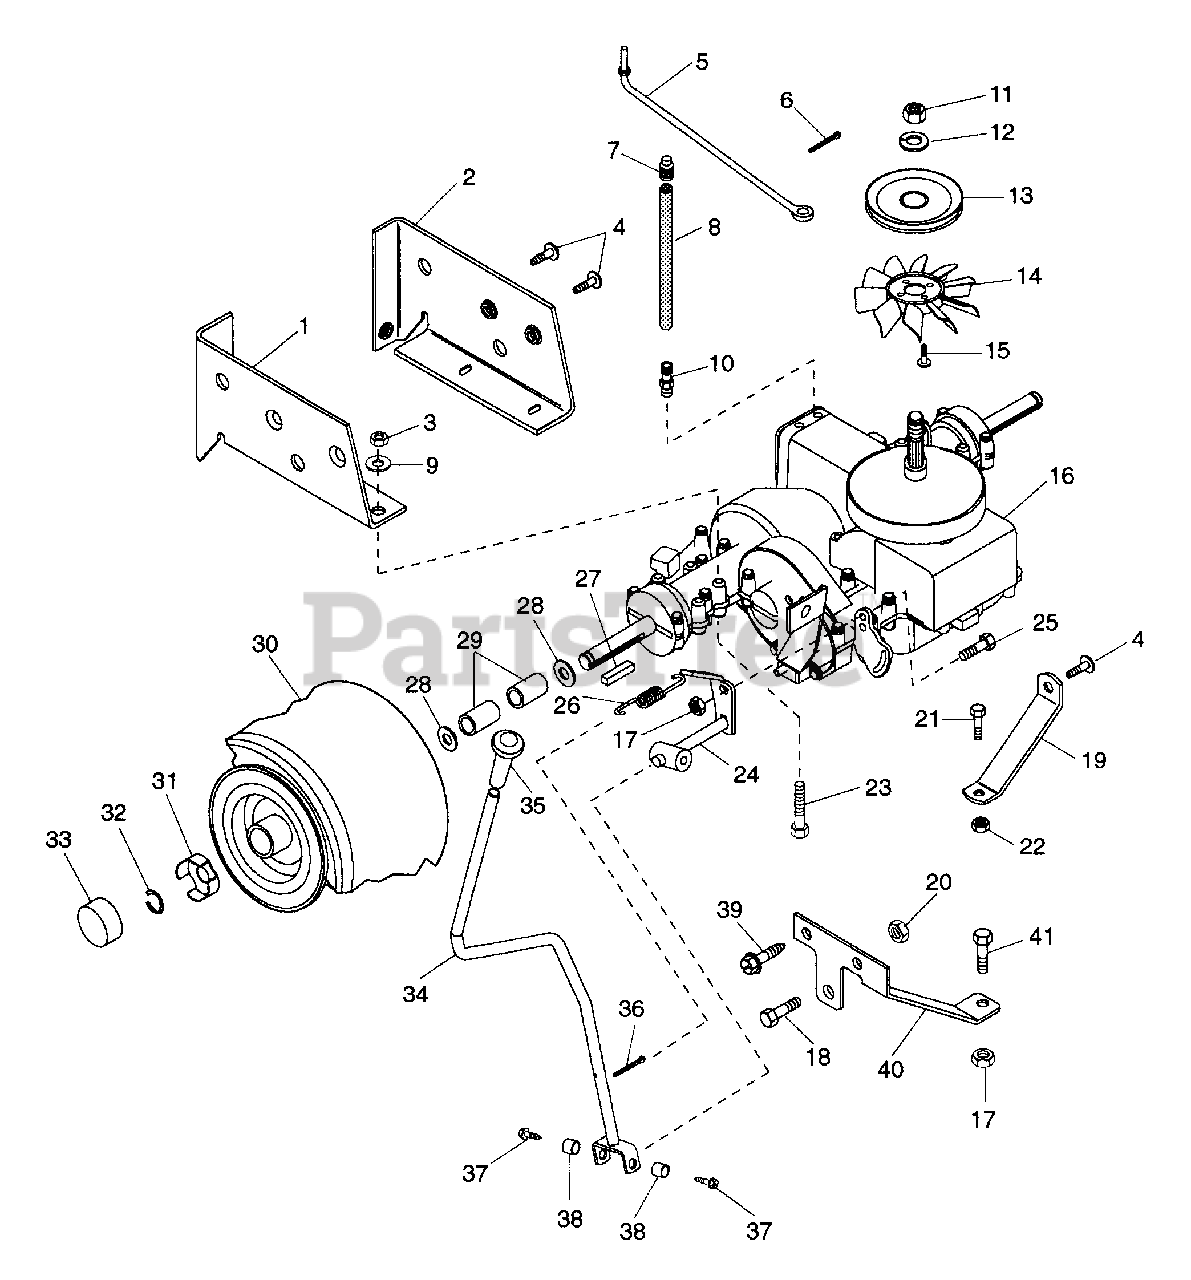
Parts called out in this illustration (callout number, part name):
1	MOUNT- TRANS. RH
2	MOUNT- TRANS. LH
3	NUT-LK-TOP .312-18 GR C PL
4	SCR-TAP .375-16X.75 HWH PL TR
5	ROD- TRANSMISSION DISCONNECT
6	PIN-COTR .09X.75 PL
7	CAP-VENT .50
8	HOSE- VENT .50ID X 7.50LONG
9	WSHR-FL-STL .328X.875X.062 PL
10	FTG-STR .50 O-RING
11	NUT-JAM .50-20 PL
12	WSHR-LK .50 REG.
13	SHEAVE - TRANSAXLE
15	SCR-TAP 10-32X.62 HWH PL T
16	TRANSAXLE- HYDRO #312-0750 IHT
17	NUT-LK .312-18 GR A PL
18	BLT-HEX .38-16X.75 PL GR5
19	TORQUE STRAP- LH
20	NUT-LK TOP .375-16 GR C YWZC
21	BLT-HEX .31-18X1.50 PL GR5
22	NUT-LK-NYL.312-18 PL
23	BLT-HEX .31-18X2.50 PL GR5
24	ARM - SHIFT
25	BLT-HEX .31-18X.75 PL GR2
26	SG-TENS .092X.69X1.75 WLD 54
27	KEY-SQ .188X2.0X.188 SAE 8630
28	WSHR-FL-STL .755X1.375X.062 PL
29	BSHG-SLV .750X1.125X1.062
30	T/WHL ASSY 20X8.00-8
30	RIM
30	TIRE 20X10-8 2P TS TL
31	SPINDLE CUP
32	RG-RTNG-EXT .750X.050
33	HUB CAP
34	LEVER - SHIFT
36	PIN-COTR .12X1.0 PL
37	SCR-TAP .312-18X.75 HWH PL TR
38	SPACER BUSHING .5 X .32 X .21
39	SCR-TAP .312-18X.50 HWH PL TR
40	TORQUE STRAP- RH
41	BLT-HEX .31-18X2.25 PL GR5
